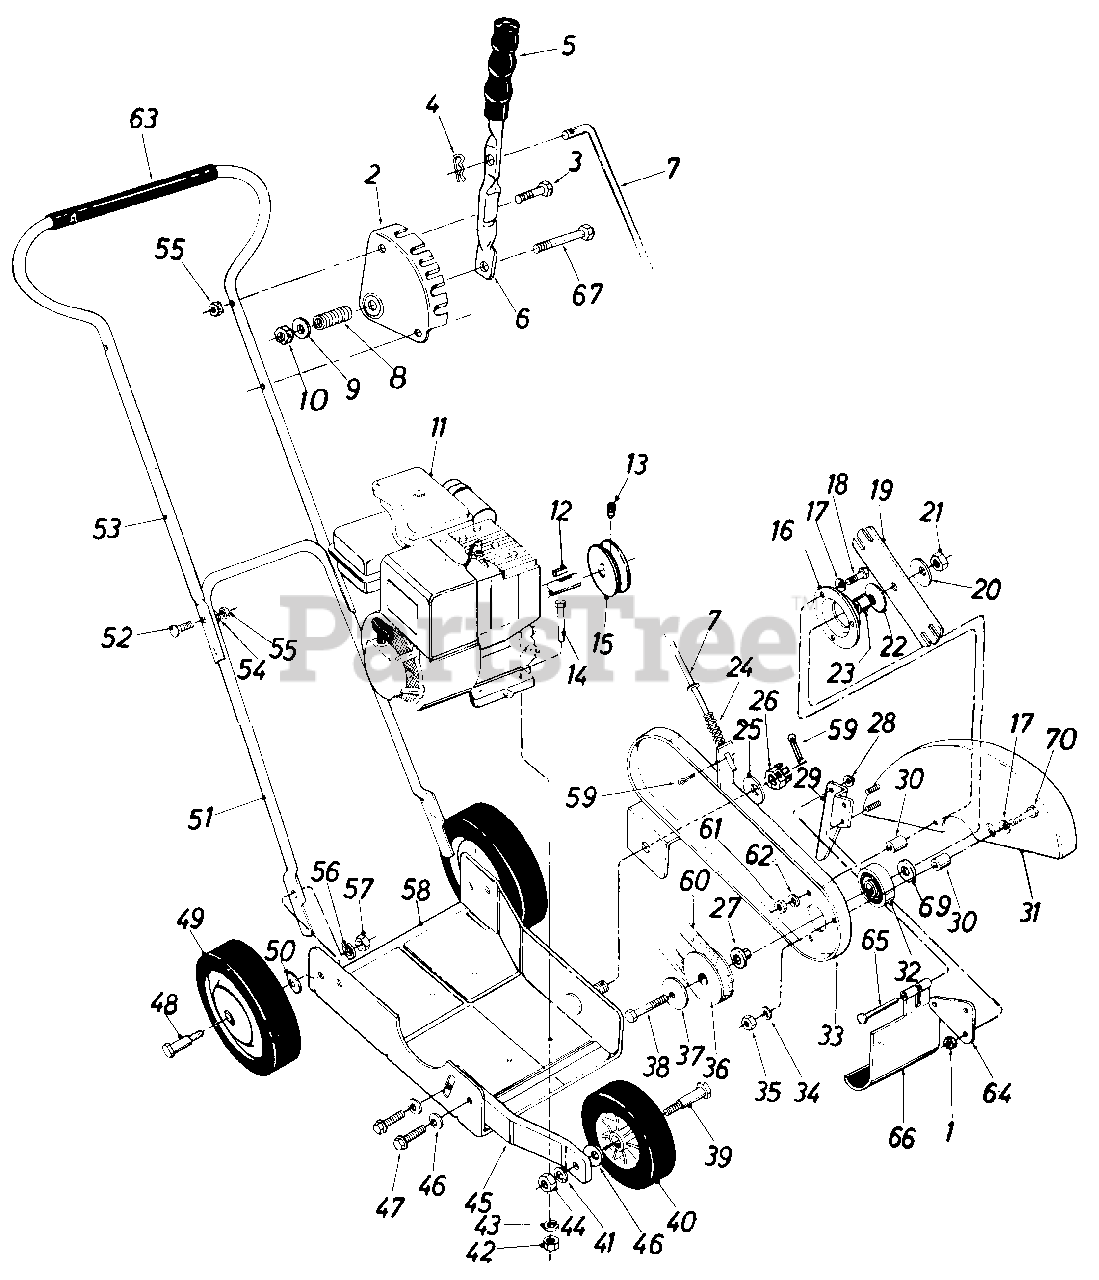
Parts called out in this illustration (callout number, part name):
1	Hex Cent. L.-Nut 1/4-20 Thd.
3	Hex Bolt 1/4-20 x 1.25" Lg.*
4	Cotter Pin 1/8" Dia. x 1.0" Lg.*
5	Grip
7	Clutch Rod
8	Compression Spring .50" O.D. x 1.38" Lg.
9	Fl.-Wash. .34" I D x .62" O.D. x .063
10	Hex Cent. L. Nut 5/16-18 Thd.
11	Engine
12	Sq.Key 3/16 x 1.0" Lg.*
13	Set Scr. 1/4-28 x 1/4" Lg.
14	Hex Bolt 5/16-18 x 1.50' Lg.*
15	Engine Pulley
16	Bearing Housing
17	Bell.-Wash. .34" I.D. x 88" O.D. x .060
18	Hex Bolt 5/16-18 x 1.25" Lg.*
20	Bell.-Wash. .535" I.D. x 1.50" O.D. x .052
21	Hex Cent. L.-Nut 1/2-20 Thd.
22	Bell.-Wash. .535" I.D. x 1.50" O.D. x .052
23	Spacer
24	Compression Spring .57" O.D. x 1.92" Lg.
25	Bell.-Wash. .535" I.D. x 1.50" O.D. x .052
26	Hex Castle Nut 1/2-20 Thd.
27	Shoulder Spacer
28	Push Cap
29	Guide
30	Spacer .354" I.D. x .635" O.D. x .510" Lg.
33	SpindleBracketAss'y.
34	L.-Wash. 5/16" I.D.*
35	Hex Nut 5/1 6-1 8 Thd.
36	Pulley
37	Bell.-Wash. .535" I.D. x 1.50" O.D. x .052
38	Hex Bolt 1/2-20 x 3.50" Lg.*
39	Shoulder Bolt .498" Dia. x 1 .450
40	Wheel Ass'y. Comp. 6" Dia. x 1.50
41	L.-Wash. 3/8" I.D.*
42	Hex Nut 5/16-18 Thd.*
43	L.-Wash.5/16" I.D.*
44	Hex Nut 3/8-16 Thd.*
45	Front Wheel Support
46	Bell.-Wash. .400" I.D. x 88" O.D. x .060
47	Hex Wash. Hd. Self Tap Scr. 3/8-16 x .75" Lg.
48	Shoulder Bolt .498" Dia. x 1 .450
49	Wheel Ass'y. Comp. 7" Dia. x 1.50
50	Bell.-Wash. .400" I.D. x 88" O.D.
51	Lower Handle
52	Carriage Bolt 1/4-20 x 1.25" Lg.*
53	Upper Handle
54	L.-Wash. 1/4" I.D.*
55	Hex Nut 1/4-20 Thd.*
56	L.-Wash. 3/8" I.D.*
57	Hex Nut 3/8-16 Thd.*
58	Base Ass'y.
59	Cotter Pin 1/8" Dia. x 1.0" Lg.*
60	3V-Belt 31.2" Lg.
61	Hex Nut 5/16-18 Thd.*
62	L.-Wash. 5/16" I.D.*
63	Grip
64	Flap Bracket
65	Hinge Pin
66	Debris Deflector
67	Hex Bolt 5/16-18 x 1.75" Lg.
69	Fl.-Wash. .51 I.D. x 1.00 O.D. x .060
70	Hex Bolt 5/16-18 x 2.00" Lg.*
